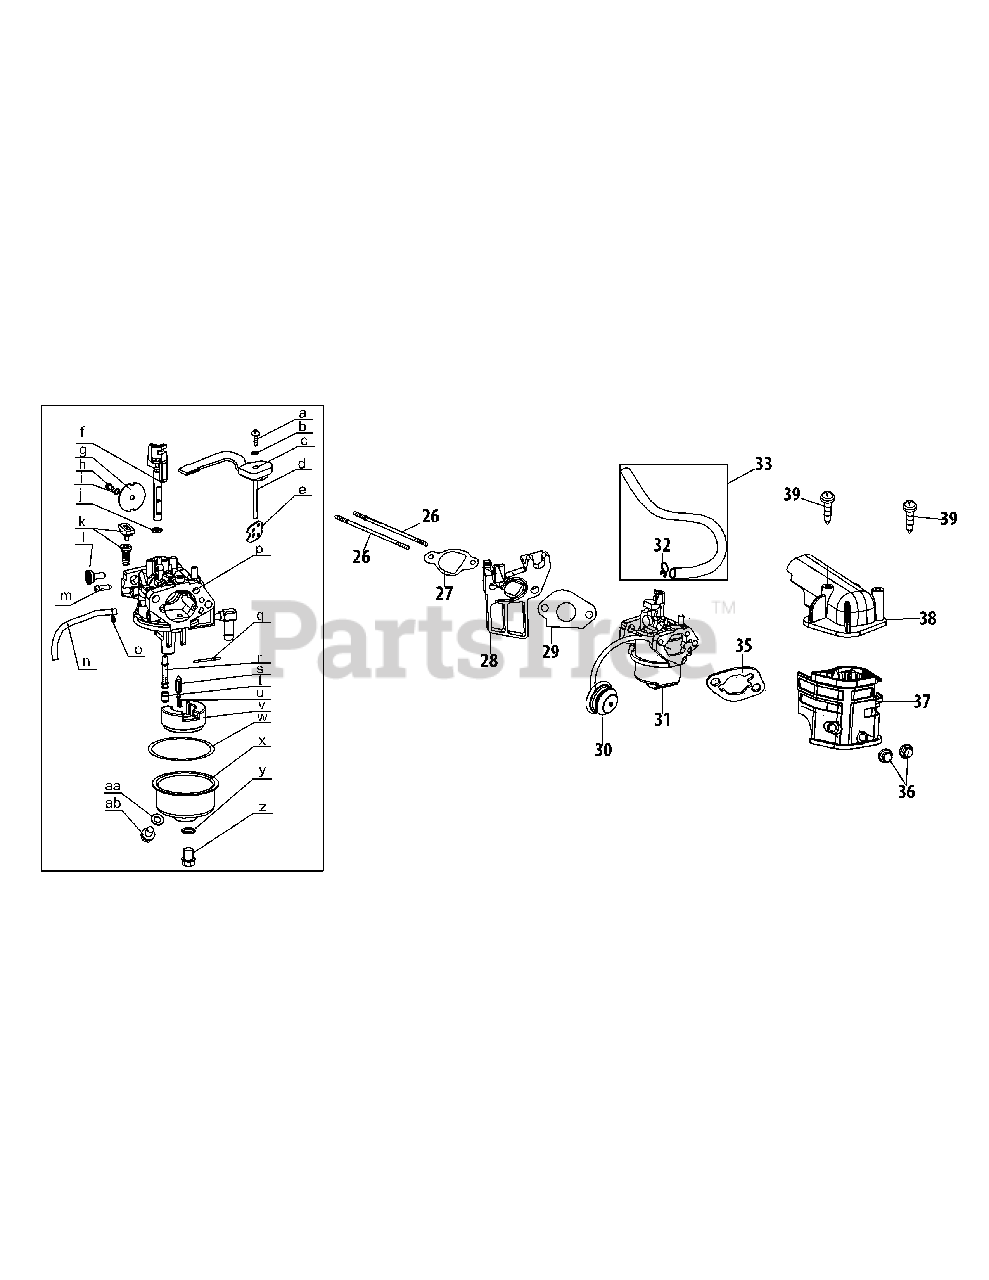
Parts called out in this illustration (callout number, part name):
26	Stud M6×110
27	Carburetor Insulator Gasket
28	Carburetor Insulator
29	Carburetor Gasket
30	Primer Assembly
30	Primer Bulb
31	Carburetor Assembly
32	Fuel Hose Clamp
33	Fuel Line Kit
35	Carburetor Gasket Plate
37	Air Cleaner Housing
38	Air Cleaner Assembly
39	Self-Tapping Bolt M4.2×16
